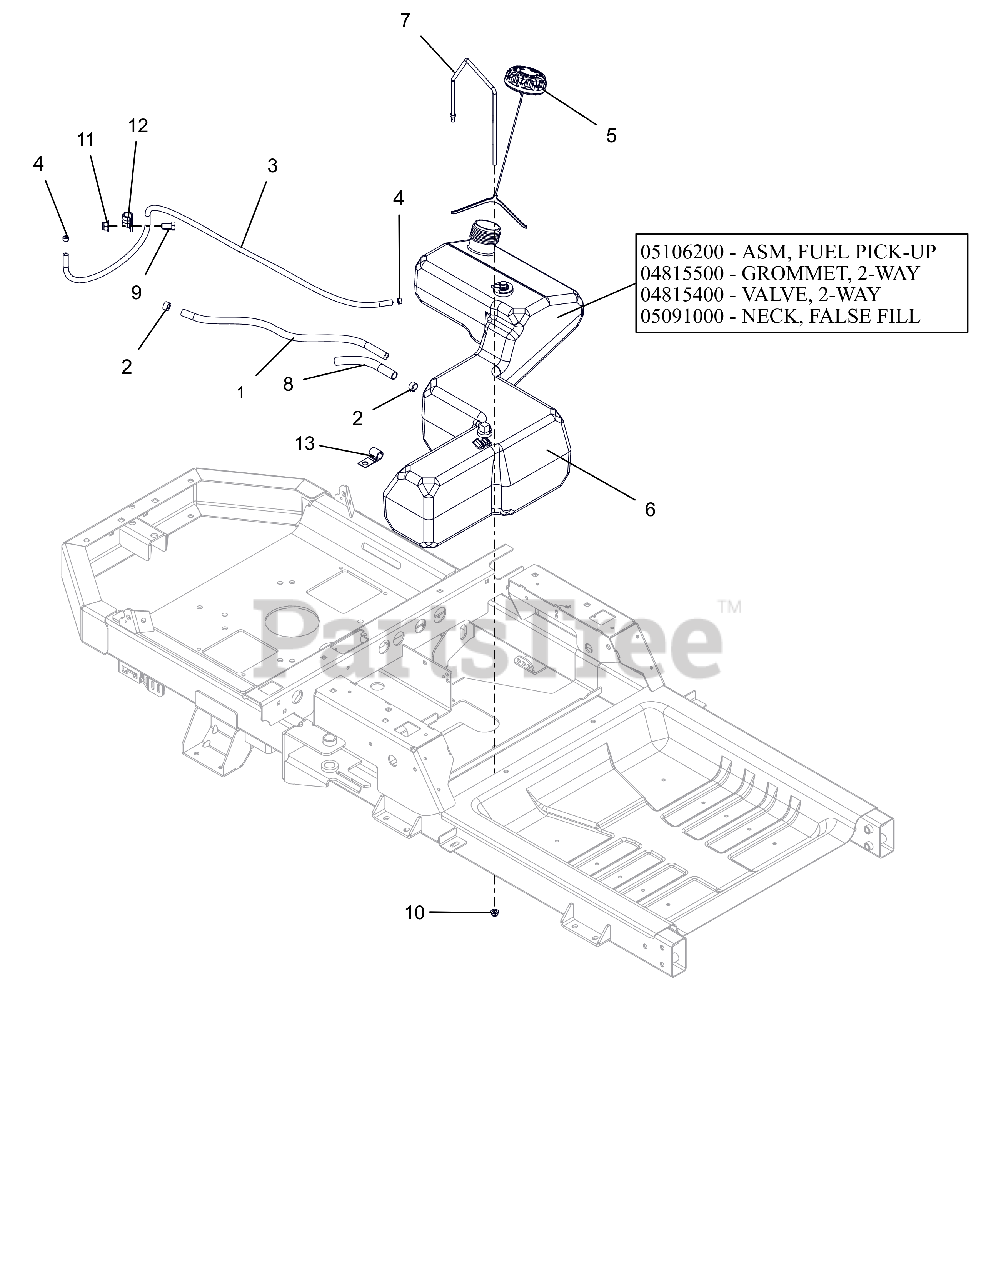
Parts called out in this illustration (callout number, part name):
1	HOSE, .25 LOW-PERM BULK GAS
2	CLAMP, FUEL LINE
3	HOSE, .188 LOW-PERM BULK GAS
4	CLAMP-HOSE, SPRING .188
5	CAP, FUEL VENT-IN 2.25" RATCH.
6	ASSEMBLY, FUEL TANK IKON(2017)
6	ASM, IKON FUEL PICK-UP
6	GROMMET, 2-WAY
6	VALVE, 2-WAY
6	NECK, FALSE FILL-2017 IKON
7	BRKT, FUEL TANK HOLD DOWN
8	WRAP, ANTIABRASION .5X.064WALL
9	@BLT-HEX .38-16X.75 GR5 YWZC
10	@NUT-LK-NYL-FLG .25-20 YWZC
11	@NUT-LK-NYL-FLG .38-16 YWZC
12	CLAMP, CUSHIONED STEEL
13	J-CLAMP
